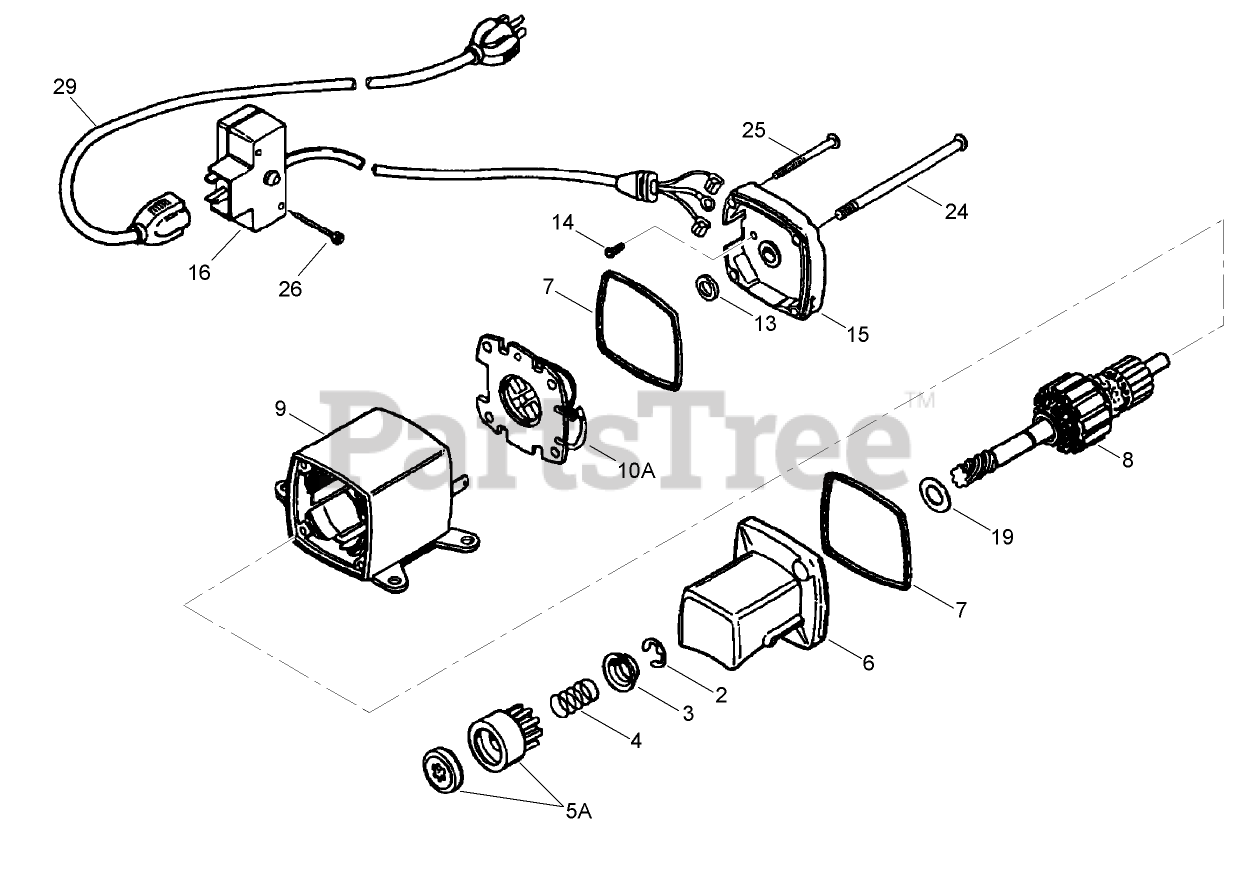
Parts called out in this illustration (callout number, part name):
2	Retainer-Ring
3	Retainer-Spring
4	Spring-Anti Drift
5A	Nut and Gear ASM (Includes 2)
6	Cap Assembly (Incl. Ref. #7)
7	O-Ring
8	Armature
9	Loose Parts Package
10A	Brush Card ASM
13	Washer-Thrust
14	Screw-Ground
15	Cap Assembly (Incl. Ref. #7)
16	Switch Box Asm
19	Washer-Thrust
24	Bolt-Case
25	Screw-Ground
26	Screw (O.E.M. supplied)
29	Cord-Extension (10-6)
